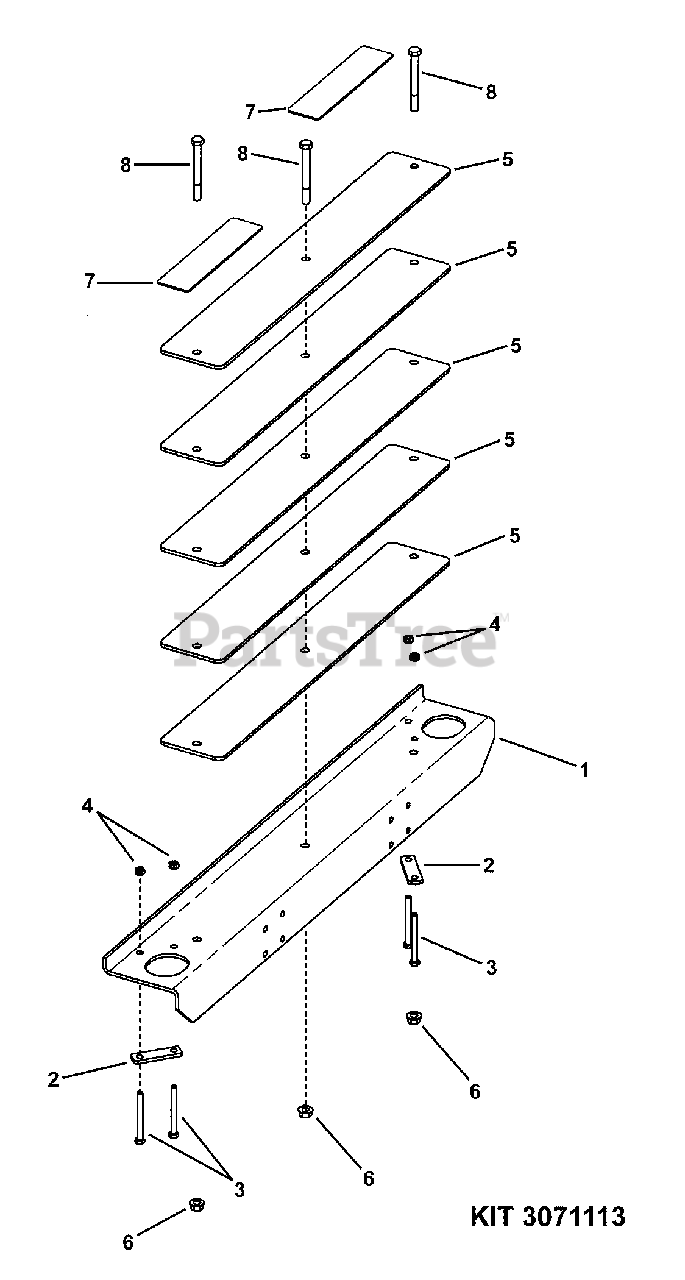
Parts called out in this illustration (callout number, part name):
1	CHANNEL, Weight Mounting
2	BAR, Clamp
3	BOLT, 3/8-16 x 4" Hex Head Cap, GR 5
4	NUT, 3/8-16 Hex Center Lock
5	WEIGHT, NZM Weight Kit
6	NUT, 1/2-13 Hex Flange Lock
7	PAD, Anti-Skid, Weight Kit
8	SCREW, 1/2-13 x 4-1/2" Hex Head Cap
